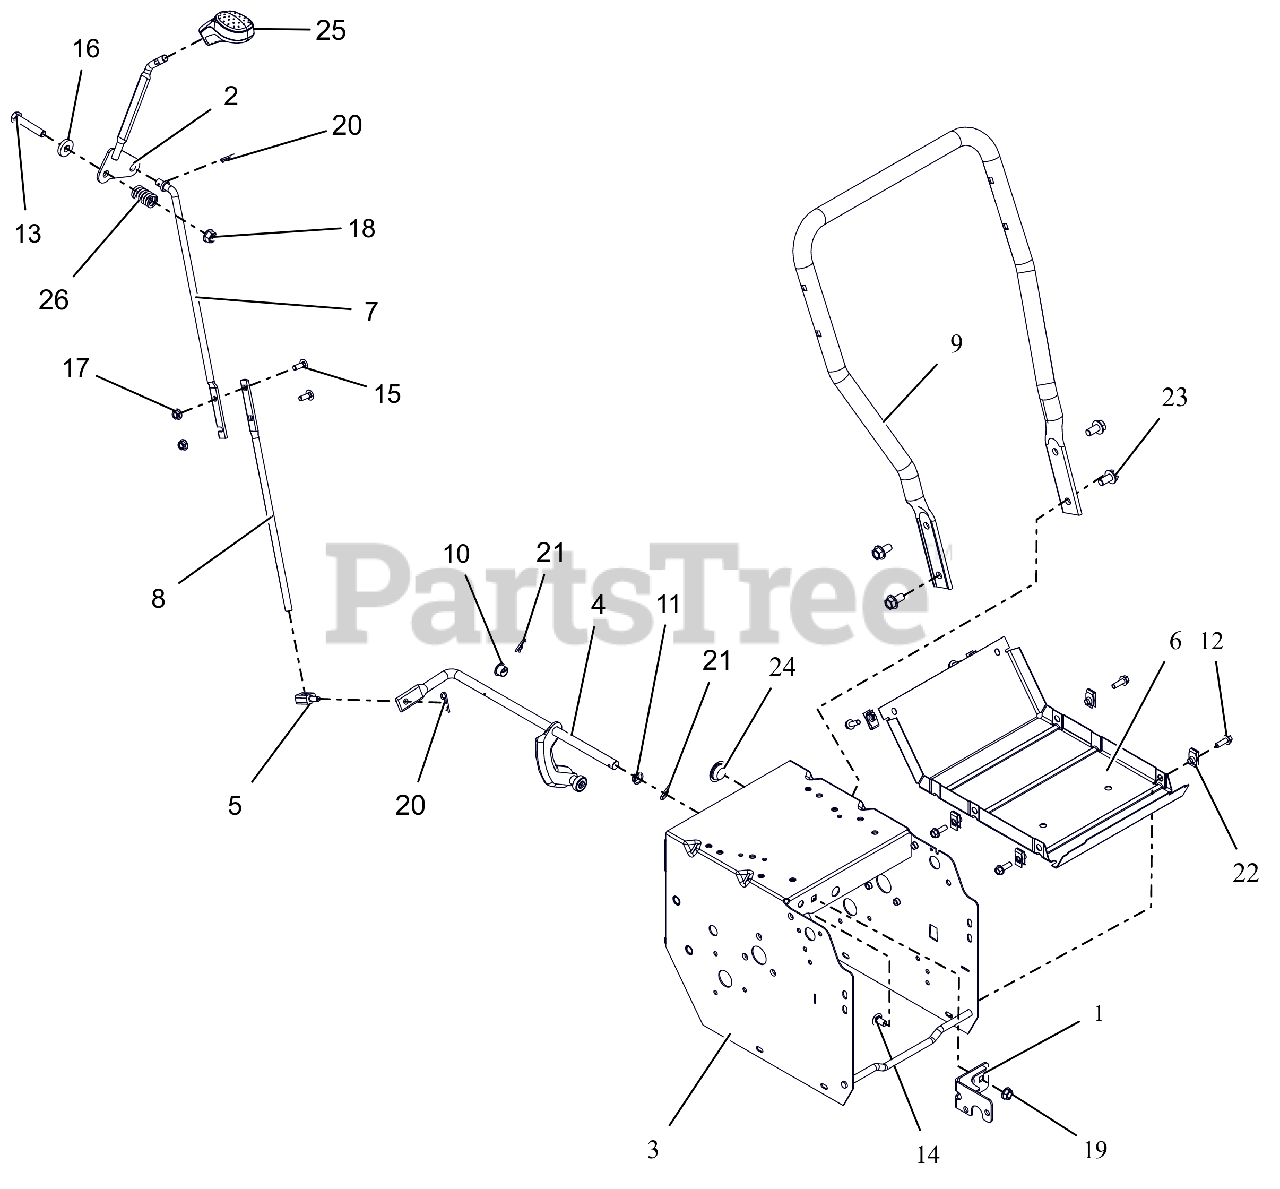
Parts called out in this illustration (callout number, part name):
1	WELDMENT, FRAME BRACKET
2	LEVER, CONTROL-SHIFT(WELDMENT)
3	WELDMENT, FRAME - DELUXE 16"
4	ARM, SHIFT-SMALL DASH (ASSY)
5	PIVOT,SHIFT ROD .375-16(TRUNN)
6	COVER, BOTTOM
7	ROD, SHIFT - UPPER
8	ROD, SHIFT - LOWER(SMALL DASH)
9	HANDLEBAR, LOWER - SM DELUXE
10	BUSHING, POLYLINER-.50 SPLIT
11	BUSHING, POLYLINER-.50 SNAPIN
12	BLT-HEX .25-20X.75 HWH YZ GR5
13	@BLT-HEX .38-16X2.00 GR5 YWZC
14	@BLT-RHDSSQNK .31-18X.62 G5YZ
15	@BLT-RDHDSQNK .25-20X.75 G5YZ
16	WSHR-FL-STL .406X1.00X.188 YWZ
17	@NUT-LK-CTR-FLG .25-20 YWZC
18	@NUT-LK-TOP-FLG .38-16 YWZC
19	@NUT-LK-TOP-FLG .31-18 YWZC
20	PIN-HAIR INT .08X.18X1.18 YWZC
21	CLIP, SPRING
22	NUT-RTNR .25-20X.56
23	BLT-SERHFWH .38-16X.75 YWZC
24	PLUG, HOLE - .875" NYLON
25	KNOB, CONTROL, DASH
26	SG-COMP .125X.781X1.250
